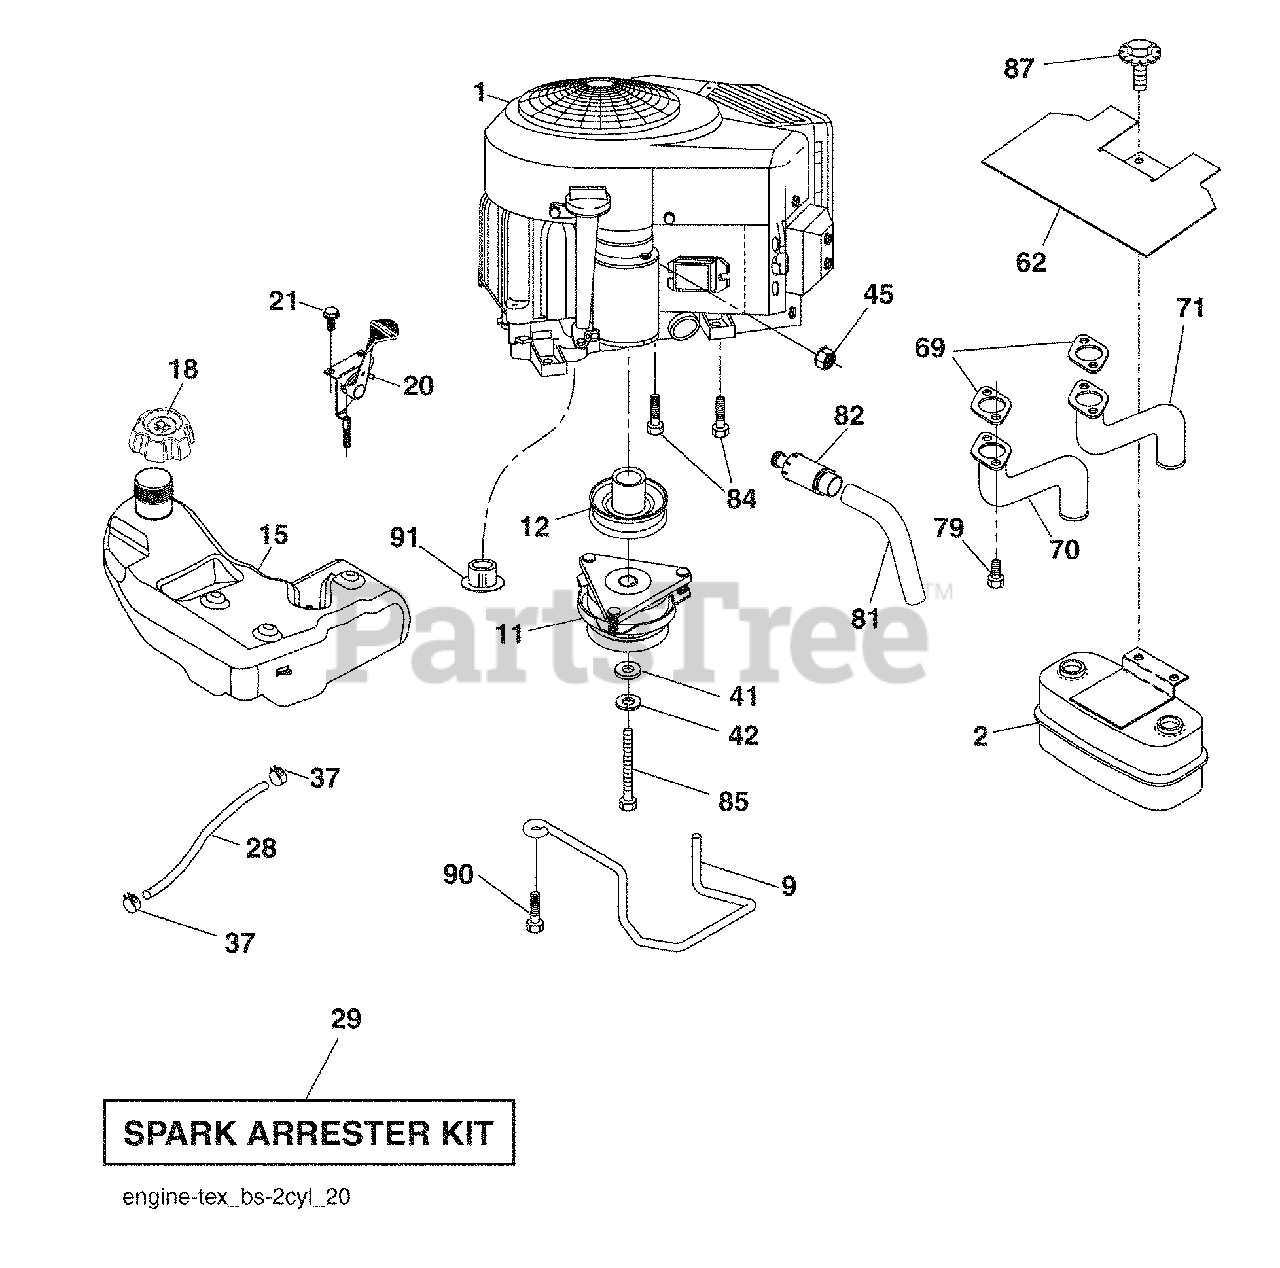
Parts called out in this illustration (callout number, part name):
9	Keeper Belt Engine
11	Clutch Electric
12	Pulley Engine
15	Tank Fuel 4.0
18	Cap Asm
20	Control Throttle
21	Screw #10 x 0.750 BOS Thread
28	Fuel Line
29	Spark Arrester Kit
37	Clamp Hose
41	Washer 1-1/2 OD x 15/32 ID x .250
42	Washer Lock 7/16
45	Nut Keps Hex 1/4-20 unc
62	Shield Heat Muffler
70	Tube Exhaust LH
71	Tube Exhaust RH
79	Screw Socket Head 5/16-18 x 1
81	Tube Drain Oil Easy
82	Plug Drain Oil
84	Screw 3/8-16 x 1-1/4
85	Bolt Hex 7/16-20 x 3.75 Gr. 5
87	Bolt 5/16-18 x 3/4
90	Screw 3/8-16 x 1
